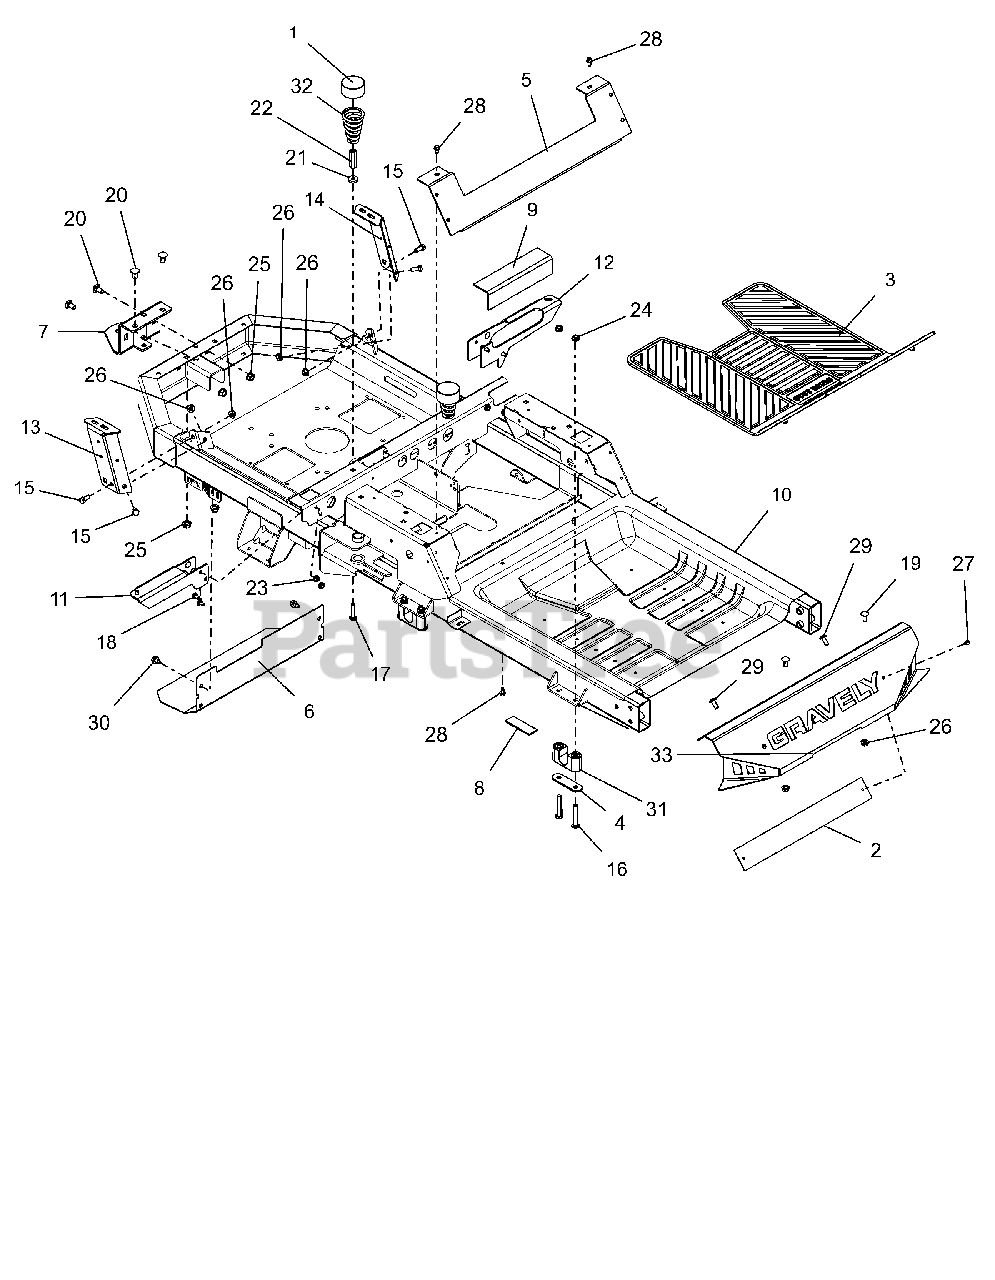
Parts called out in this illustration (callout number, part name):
2	PLATE, BACK FOOT-REST XL
3	FLOOR MAT, RUBBER - GRAVELY
4	PLATE, BEARING SUPPORT
5	PLATE, SEAT KICK
6	HEAT, SHIELD
7	BRKT, HITCH TONGUE
8	PAD,RBR 1.0"X3.0" W/ADHESIVE
9	PAD, RUBBER-TANK
10	KIT, ZT-X/XL FRAME SERVICE
11	BRKT,CROSS EXTENSION - LH
12	BRKT,CROSS EXTENSTION - RH
13	MOUNT,FENDER-RH EXTENSION
14	MOUNT,FENDER-LH EXTENSION
15	@BLT-HEX .31-18X.75 GR5 YWZC
16	BLT-RDHDSQSHNK .31-18X2.25 YWZ
17	@BLT-RDHDSQNK .31-18X1.50 G5YZ
18	BLT-RDHDSQSHNK.25-20X.50 YWZC
19	@BLT-RDHDSQNK .31-18X.75 G5YZ
20	@BLT-RDHDSQNK .38-16X.75 G5YZ
21	WSHR-FL-STL .328X.87X.179 YWZC
22	NUT, COUPLING 5/16-18 X 1 3/4
23	NUT-LK-CTR-FLG .25-20 YWZC
24	@NUT-LK-CTR-FLG .31-18 YZ GR F
25	@NUT-LK-TOP-FLG .38-16 YWZC
26	@NUT-LK-TOP-FLG .31-18 YWZC
27	RIVET, .1875 AL/AL .126-.250
28	SCR-TAP .25-20X.50 HWH TR YWZ
29	SCR-RDHDSKTAP .31-18 X .75
30	@SCR-TAP .31-18X.50 HWH TR YWZ
31	BSHG, DECK LIFT PIVOT
32	SPRING, SEAT
33	KIT,FOOTPLATE W/DECAL G- XL
